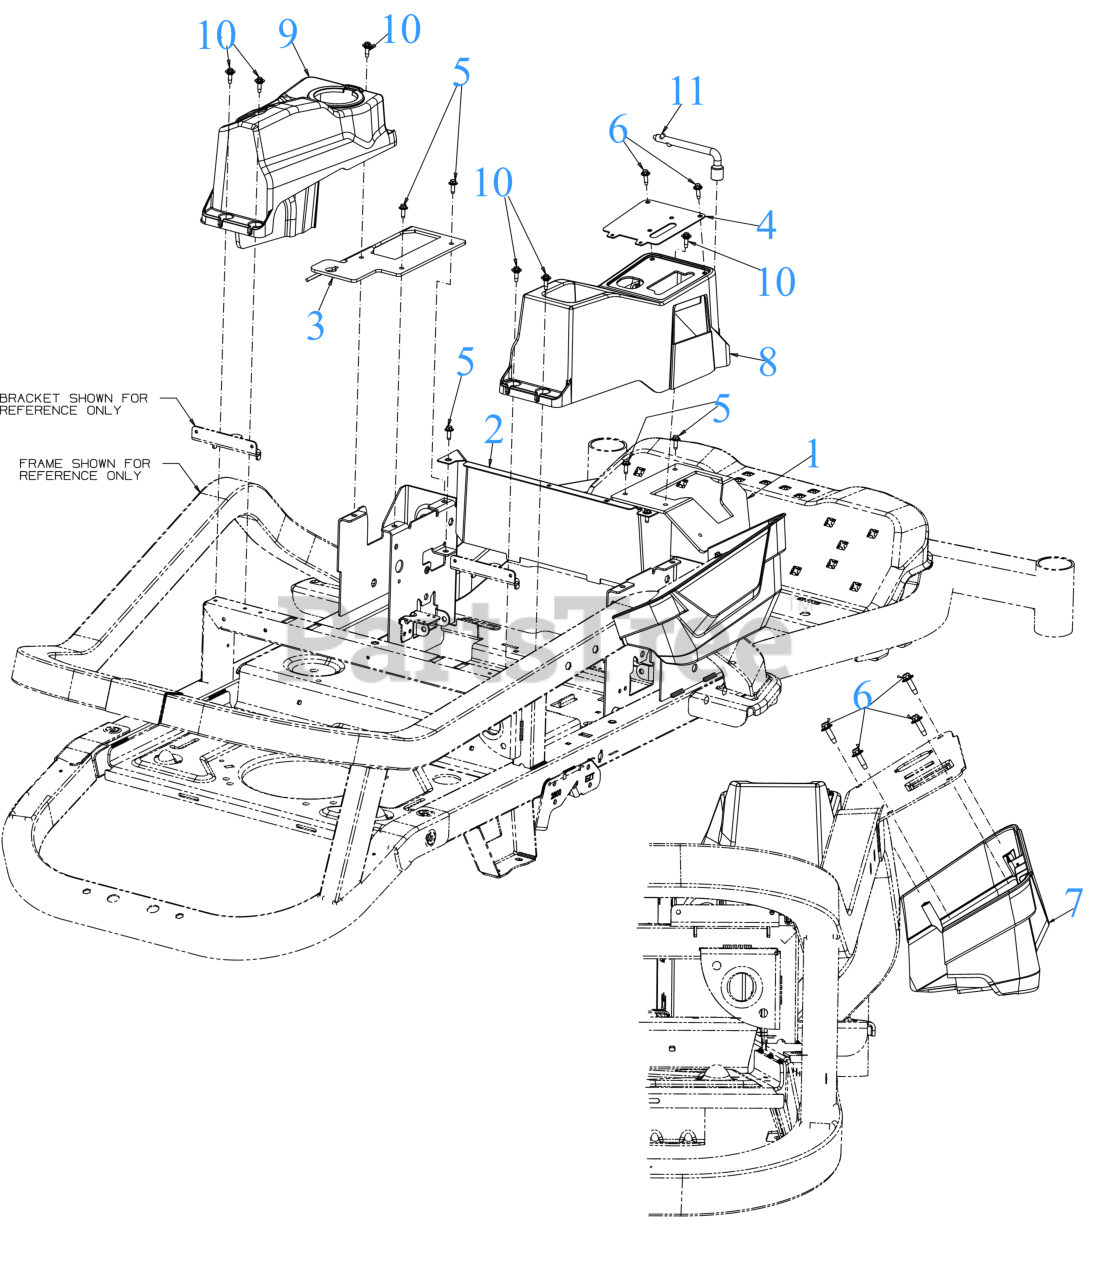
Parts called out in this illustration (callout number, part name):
1	CONTROL BRACKET (RH)
2	SEAT BOX FRONT PLATE
3	CONTROL BRACKET (LH)
4	THROTTLE COVER (RH)
5	SCREW M6-1 x .625
6	SCREW 1/4-10 x .750
7	CONTROL PANEL CONSOLE
8	CONSOLE (RH)
9	CONSOLE (LH)
10	SHOULDER SCREW M6-1 .368 X.115
11	MULTI TOOL-1/2" SOCKET
